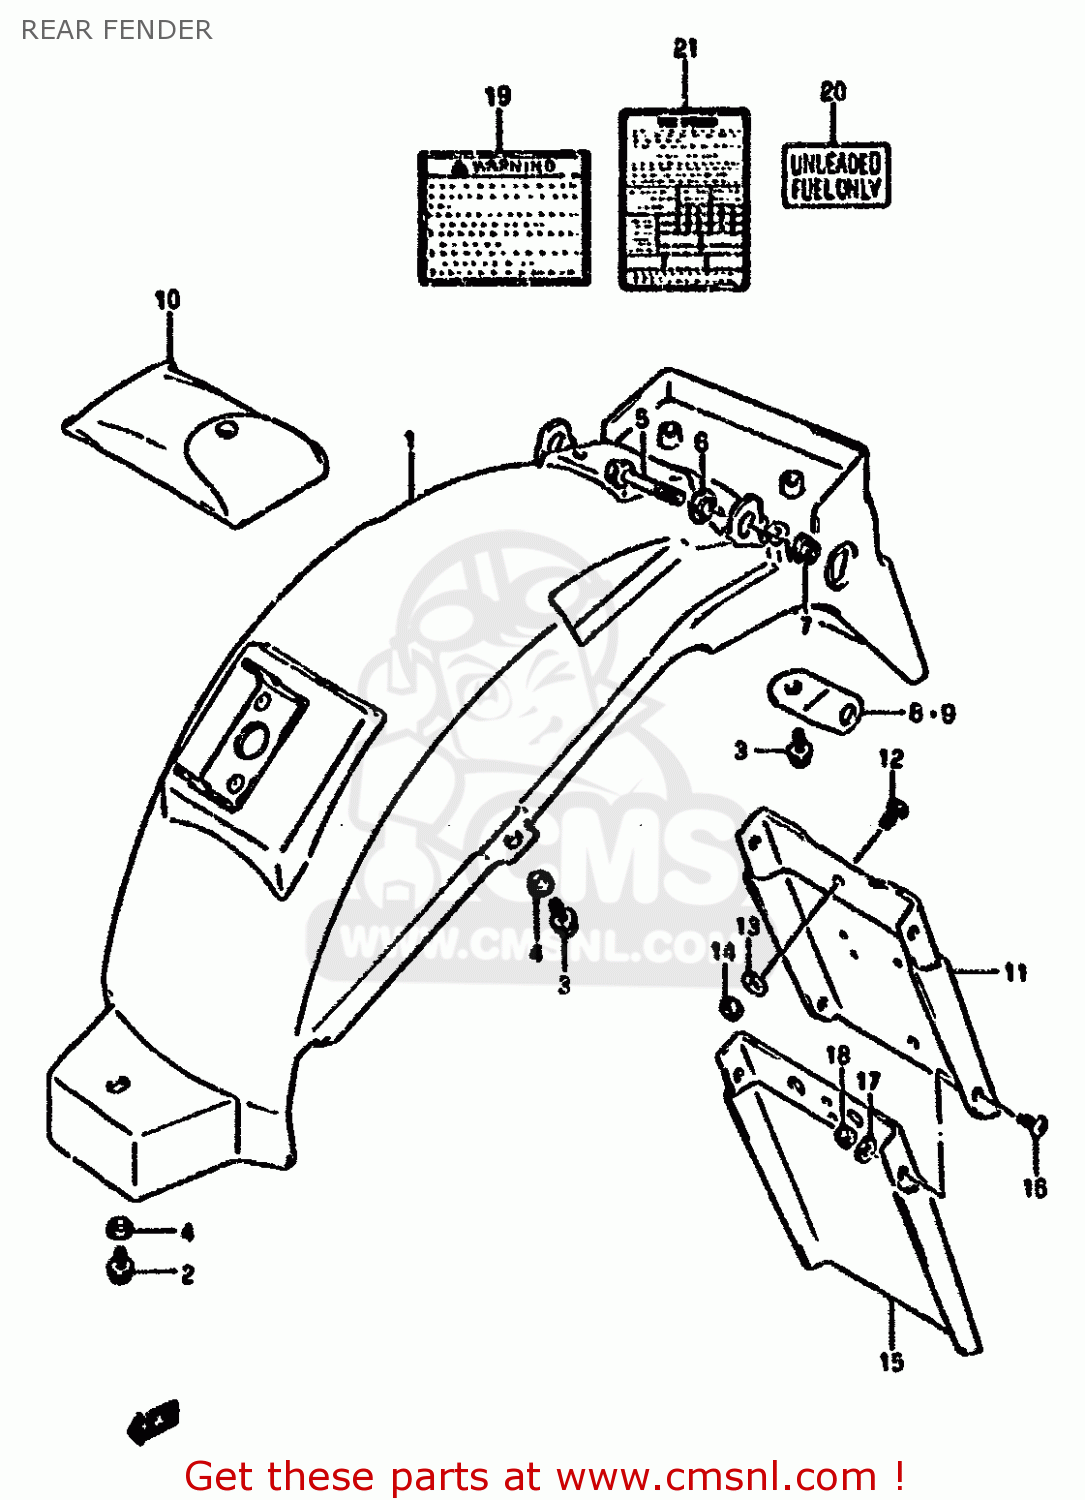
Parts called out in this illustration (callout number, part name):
1	FENDER,REAR
2	BOLT
3	BOLT
4	WASHER
5	BOLT
6	WASHER
7	NUT
8	REINFORCEMENT,REAR TURN SIGNAL
9	REINFORCEMENT,REAR TURN SIGNAL
10	TOOL ASSY
11	EXTENSION,REAR FENDER
12	SCREW
13	WASHER(6.5X16X1.2)
14	NUT
15	MUD GUARD
16	SCREW
17	WASHER(6.5X16X1.2)
18	NUT
19	LABEL, WARNING SAFETY
20	LABEL,CAUTION
21	LABEL,TIRE AIR PRESSURE
22	MANUAL,OWNER'S
